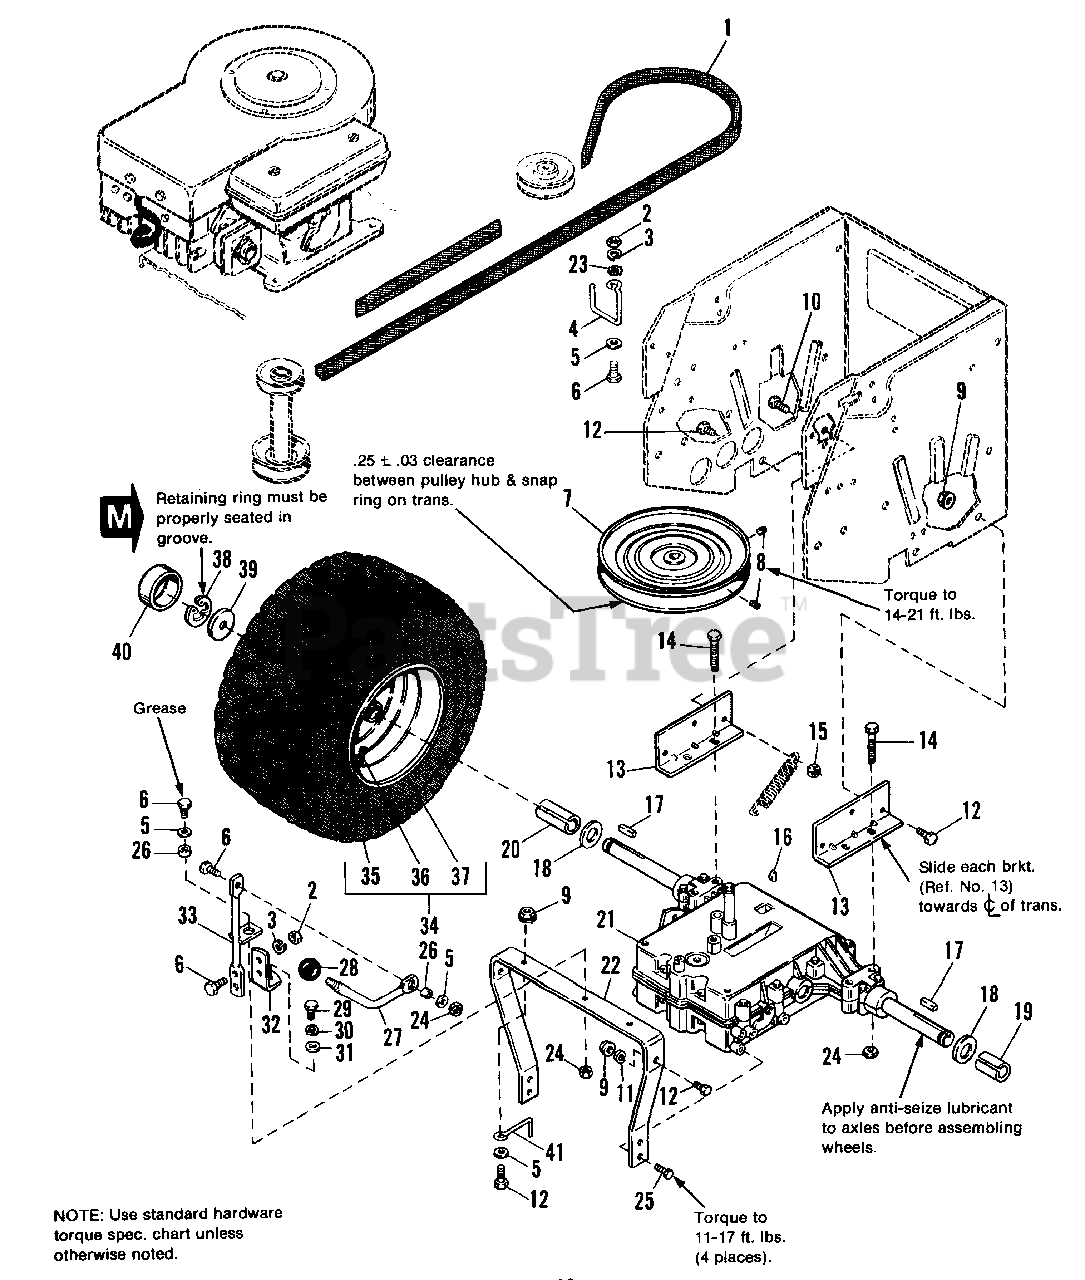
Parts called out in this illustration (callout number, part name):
2	NUT, Hex, 5/16-18
3	LOCKWASHER, 5/16
5	WASHER, 11/32
6	CAPSCREW, Hex, 5/16-18 x 1
7	PULLEY ASSY., Transmission
8	SETSCREW, 5/16-18 x 5/8
9	LOCKNUT, Hex, Flange, 3/8-16
10	CAPSCREW, Hex, 3/8-16 x 1-1/4
11	LOCKWASHER, 3/8
12	CAPSCREW, Hex 3/8-16 x 1
13	SUPPORT, Transmission, Rear
14	CAPSCREW, Hex, 5/16-18 x 2-1/4
15	LOCKNUT, Hex, 3/8-16
16	KEY, Woodruff, #9
17	KEY, 3/16 x 3/16 x 1-1/2
18	WASHER, 15 Ga.
21	TRANSAXLE, 5 Speed, Peerless
22	SUPPORT, Transmission, Front
23	LOCKWASHER, Ext.
24	LOCKNUT, 5/16-18
25	SCREW, Taptite, 5/16-18 x 5/8
28	KNOB, Ball, Shift
29	CAPSCREW, Hex, 1/4-28 x 5/8
30	LOCKWASHER, 1/4
31	WASHER, Plain, 9/32
32	LINK, Shift, Lower
33	SHIFT LINK ASSY., Upper
34	WHEEL & TIRE ASSY., 18 x 8.50-8 (Turf Saver tire)
34	WHEEL & TIRE ASSY, 18 x 8.50-8 (Turf Mate Tire)
35	TIRE (Carlisle) 18 x 8.50-8 (Turf Saver tire)
35	TIRE (Carlisle) 18 x 8.50-8 (Turf Mate tire)
36	VALVE STEM & CAP
37	WHEEL (All Models)
40	CAP, Hub, Threaded
